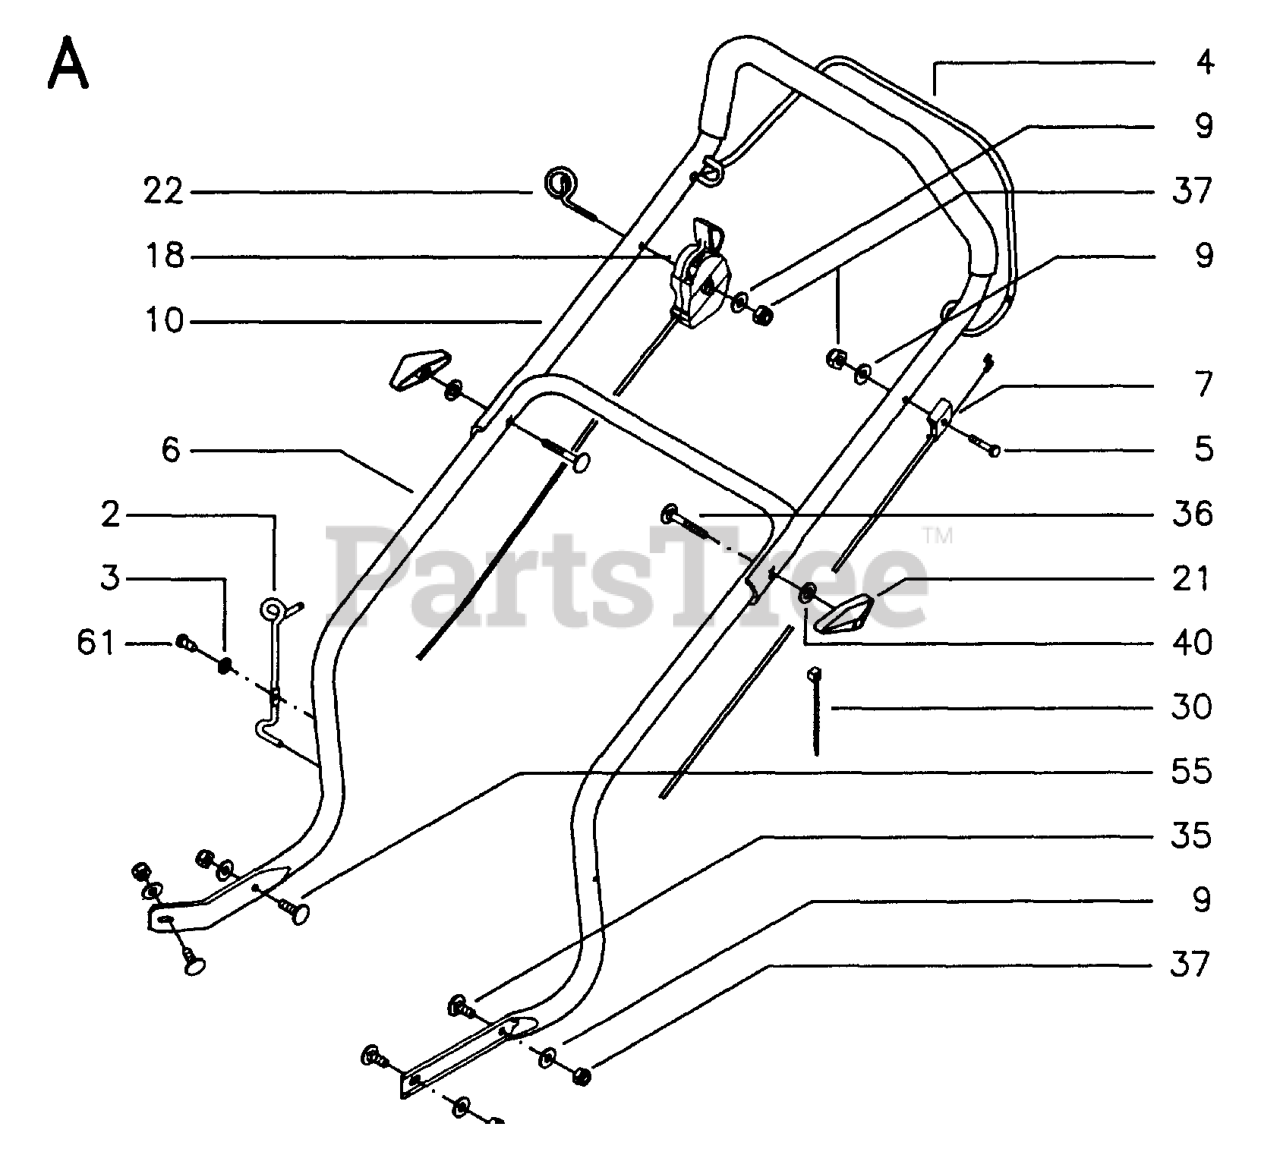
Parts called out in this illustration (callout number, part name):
5	BOLT FLANGE
7	REPL BY 532 85 16-72
18	CONTROL
21	WINGNUT
37	LOCKNUT M6
40	WASHER - 15X7.3X1.6
55	REPL BY 515 71 16-20
